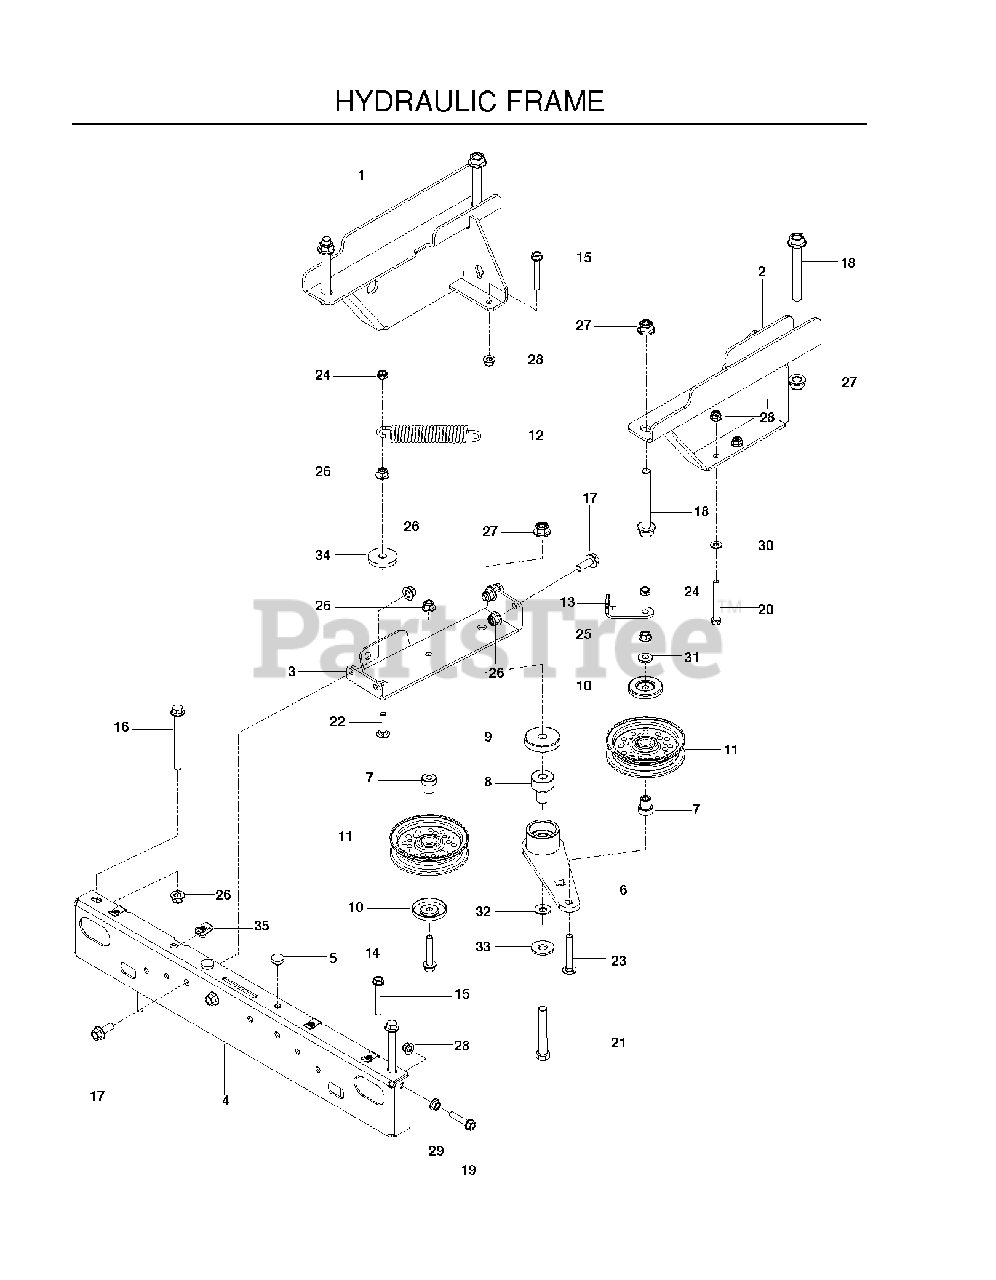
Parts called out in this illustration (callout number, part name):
1	MOUNT.ZT3400.RT.BLACK
2	MOUNT.ZT3400.LT.BLACK
3	MOUNT IDLER BLK
4	U-CLIP 5/16-18 NUT RETAINER
5	GROMMET, BUMPER
6	ARM, IDLER, STEEL, W/BGS
7	PIVOT, IDLER
8	PIVOT, BEARING
9	SHIELD, DUST
10	DUST SHIELD
11	IDLER PULLEY
12	SPRING, EXTENSION
13	BRACKET, SPRING
14	HHFS 3/8-16 X 2.0 GD 5
15	HHFS 5/16-18 X 2.25 GD 5
16	HHFS 3/8-16 X 4 GR5 ZD
17	HHFS 3/8-16 X 1 GRD 5 ZD
18	HHFS 1/2-13 X 4.0 GD8 ZD
19	HHFS 5/16-18 X 1.5 GD 5
20	HCS 5/16C X 2-3/4
21	HCS 1/2C X 3 1/4
22	RHSNB, 3/8-16 X 1-1/2
23	CARRIAGE BOLT 3/8-16 X
24	NUT HEX 3/8-16 NYLON, THIN
25	NUT 3/8C WHIZ
26	NUT 3/8-16 HEX FLG NYLOC ZD
27	NUT, 1/2-13 HEX FLG NYLOC ZD
28	5/16-18 NYLOC FLANGE NUT
29	NUT 5/16C WHIZ
30	FLAT WASHER 5/16 SAE
31	WASHER, 3/8 THICK
32	CONTACT BELLSPR 1/2
33	WASH USS FLAT 1/2
34	SPINDLE WASHER
35	U-CLIP 5/16-18 NUT RETAINER
